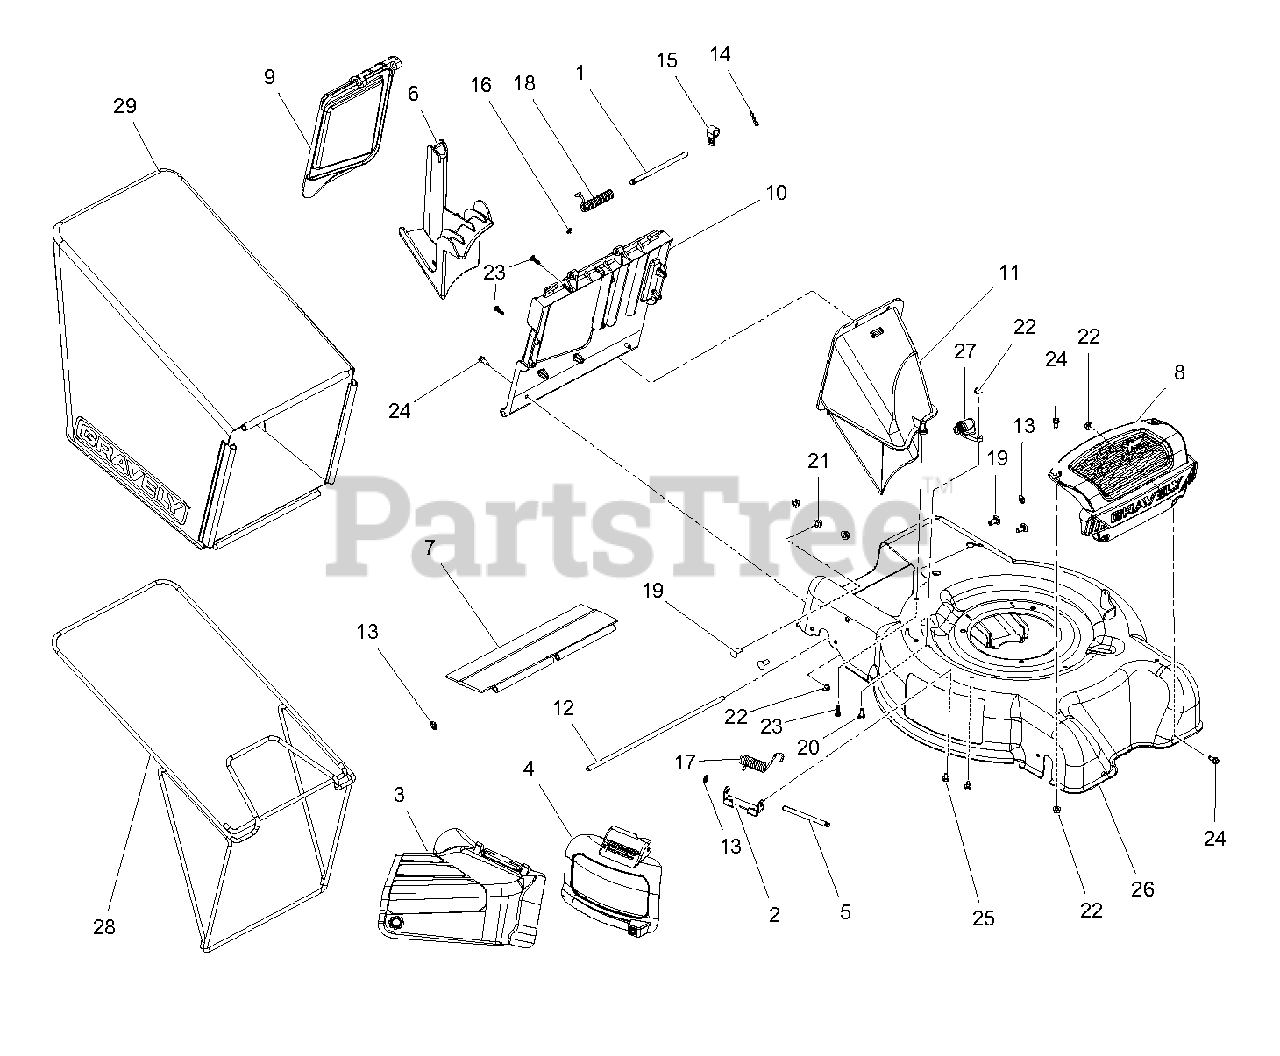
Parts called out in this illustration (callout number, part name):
1	PIN, 5/16 X 5.80"
2	BRKT, HINGE LM
3	CHUTE, SIDE DISCHARGE - LM
4	COVER, SIDE DISCHARGE - LM
5	PIN, SIDE DISCHARGE
6	PLUG, MULCH
7	GUARD, REAR
8	TRIM, FRONT
9	REAR DOOR WITH SAFETY DECAL
10	HANGER, BAG
11	CHUTE, REAR DISCHARGE
12	ROD, REAR GUARD
13	NUT, PUSH .312
14	PIN, HAIR INT .08X.18X1.18 Y
15	CLAMP, LM CABLE
16	PLUG, 5/16 HOLE, .125 MATL PLASTIC
17	SPRG, TORSION
18	SPRG, TORSION
19	@BLT-RDHDSQNK .31-18X.75 G5 YWZC
20	@BLT-HEX .25-20X.63 GR5 YWZC
21	@NUT, LK-TOP-FLG .312-18 YWZC
22	@NUT, LK-TOP-FLG .25-20 YWZC
23	SCR-TAP #12-14X.75 PLASTITE BLZC
24	SCR-TAP .25-20X.62 HWH TR YWZ
25	SCR-TAP .25-20X.37 HWH YWZ TR
26	DECK WITH SAFETY DECAL
27	ASM, WASHOUT PORT W/ O-RING
28	FRAME, BAGGER
29	BAGGER, GRASS GRAVELY
